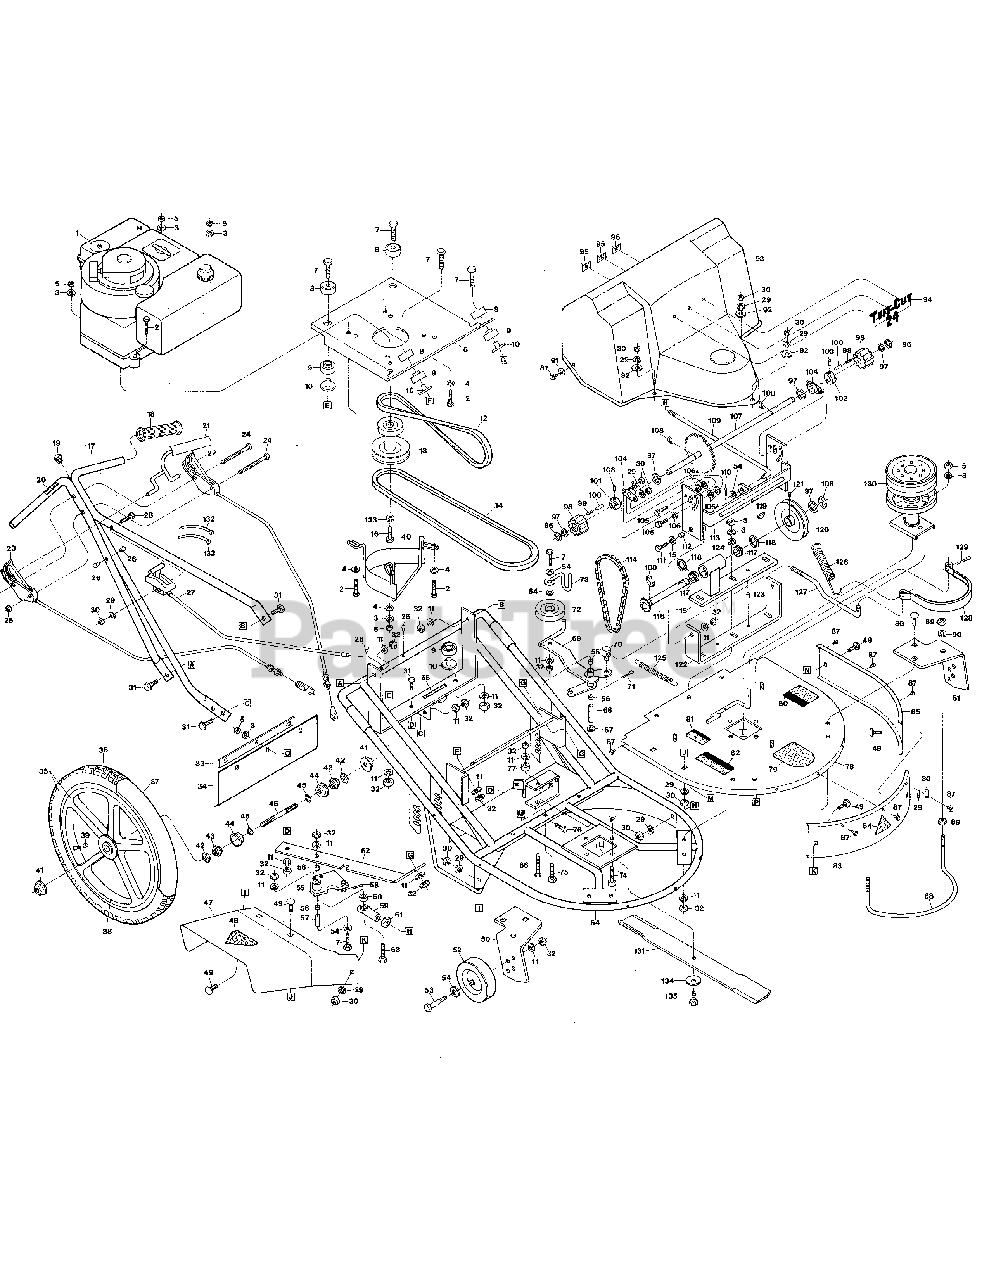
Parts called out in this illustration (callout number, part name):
2	SCR-HH 5/16-18X1.75
3	WASHER-LK .312
4	WASHER-.88X312X.08
5	NUT-HEX 5/16-18
6	BASE-ENGINE
7	SCR-HH 3/8-16X2.0 G5
8	REBOUND MOUNT-24"
9	LOAD CARRYING MOUNT-24"
10	TUB-SPACER 24"
11	WASHER-LK .375
12	TRACTION-V BELT
13	PULLEY-ENGINE
14	BLADE-V BELT
15	WASHER-1.0X.438X.104
16	SCR-HH 7/16-20X1.25 G5
17	ASSM-HANDLEBAR 22" PUSH (INCL. 18 & 20)
18	GRIP-HANDLEBAR
19	PLUG-METAL CAP
20	DECAL-STARTING INST
21	BAIL WELDMENT-SELF PROP
22	CABLE-WHEEL DRIVE (CABLE & LATCH)
23	CABLE-BLADE DRIVE (CABLE & LATCH)
24	SCR-PHP M10-24X4.0
25	NUT-HEX LOCK #10-24 PL
26	PLUG-HOLE (RECOIL START ENGINES ONLY)
27	SPEED CONTROL-ENGINE (CABLE & CONTROL)
28	SCR 1/4-20X1.5 PL CSHH
29	WASHER-LK .25
30	NUT-HEX 1/4-20
31	SCR-HH 3/8-16X.75 G5
32	NUT-HEX 3/8-16
33	BRKT-PROT TRAILER PNT
34	TRAILER-MOWER
35	ASSM-TIRE/WHL ASSEMBLY (INCL. 36-39, 41-46)
36	TIRE-20 X 2.125
37	TUBE-20"
38	ASSM-20" RIM (WHEEL ONLY)
39	CAP-VALVE
40	GUIDE-BELT PNT
41	NUT-HF/LK 3/8-24 WHIZ
42	NUT-LOCK 3/8-24 PL
43	NUT-ACORN 3/8-24
45	BEARING-WHEEL
46	AXLE-WHEEL
47	CHUTE-DISCHARGE W/DECAL (INCL. 48)
48	DECAL-BLADE WARNING
49	SCR-CARR 1/4-20X.375
50	HANGER-WHEEL (RIGHT SIDE)
51	HANGER-WHEEL (LEFT SIDE)
52	ASSM-TIRE&WHEEL 6X1.50
53	SCR-SHLDR 3/8-16X1.406
54	WASHER-FLAT 3/8 SAE
55	ASSM-BELLCRANK W/BUSHING (INCL. TWO BEARINGS REF. NO. 56)
56	BEARING-SLEEVE
57	TUBE-BELL CRANK
58	PIN-COTTER .09X.75
59	JOINT-BALL
61	NUT-HEX/JAM 3/8-24
62	STRAP-BELLCRANK
63	SCR-HH 3/8-16X1.75 GR5
64	WELDMENT-FRAME 24" (INCL. 65)
65	DECAL-CPSC COMPLIANCE
66	SCR-HH 3/8-16X4.5 G5
67	SHIM-WASHER
68	TUBE-PIVOT
69	ARM-IDLER W/BUSHINGS (INCL. TWO BEARINGS REF. NO. 56)
70	TRUNNION
71	PIN-COTTER .094X1.0
72	PULLEY-IDLER
73	GUIDE-BLADE BELT
74	SCR-HH 5/16-18X1.0 G5
75	BOLT-HH 5/16-18 X 2 G5
76	SCR-HHC 5/16-18X.75 GR 5
77	SPACER-.625X.387X1.0
78	ASSM-24" DECK TOP (INCL. 79-82)
79	DECAL-TUFFCUT LOGO
80	DECAL-WARNING PROCEDURES
81	DECAL-CAUTION BELT COVER
82	DECAL-DANGER GUARD
83	WRAP-FRONT 24" PNT (INCL. 84)
85	WRAP-LH PNT
86	SCR-CARR 3/8-16X1.00
87	SCR-HW M10-16X.75 SELT DR
88	BUMPER-24" PNT
89	NUT-HEX JAM 1/2-13
90	WASHER-LK .5
91	WASHER-#10 TYPE B PLN
92	WASHER-FLAT 1/4 SAE
93	KIT-SVC 24" BELT COVER
94	PLATE-NAME TUFFCUT
95	CLIP, NAMEPLATE MOUNTING
96	RING-HEAVY EXT .575 ID
97	WASHER-1.0X.632X.03
98	ROLLER-DRIVE
99	SPRING-DOWEL RETURN
100	PIN-DOWEL 1/4"
101	RATCHET-RH MACH
102	RATCHET-LH MACH
103	PIN-ROLL 3/16 X 1.5
105	SCR-HH 1/4-20X.75 G5
106	WASHER-FLAT 1/4 SAE
106A	WASHER-FLAT 1/4 SAE (USED FOR SHIMMING, AS REQUIRED)
107	WELD-AXLE 24" DRIVE SHAFT
108	RING-RETAINING "E"
109	ROD-WHEEL DR LINK 24"
110	CLIP-HITCH PIN #13 PL
111	SCR-HH 3/8-16X1.0 G5
112	SPACER-.390X.630X.281
113	ASSM-TRACTION BRKT
114	CHAIN #35-46 PITCHES
115	BRKT-JACKSFT MTG PNT
116	JACKSFT-WELD HEAT TREAT
117	BEARING
118	RING-RETAINING EXTERNAL
119	KEY-HI PRO 1/8X1/2
120	PULLEY-WHEEL DRIVE
121	SCR-SET 1/4-20X1/4
122	BRKT-U CHANNEL PNT
123	PIN-ROLL 1/4X1/2
124	WASHER
125	SPRING-WHEEL OR RETURN
126	SPRING-SPINDLE BRAKE
127	ROD-BRAKE ENGAGEMENT
128	BRAKE BAND & LINING
129	PIN-COTTER .125X.750
130	KIT-SPINDLE TUFFCUT I&II
131	BLADE-24" TUFFCUT
132	TIE-RED
133	WASHER-LK 7/16 MD SPR PL
134	WASHER-BELLEVILLE 3/8
135	SCR-HH 3/8-24 X 1.5" G8
